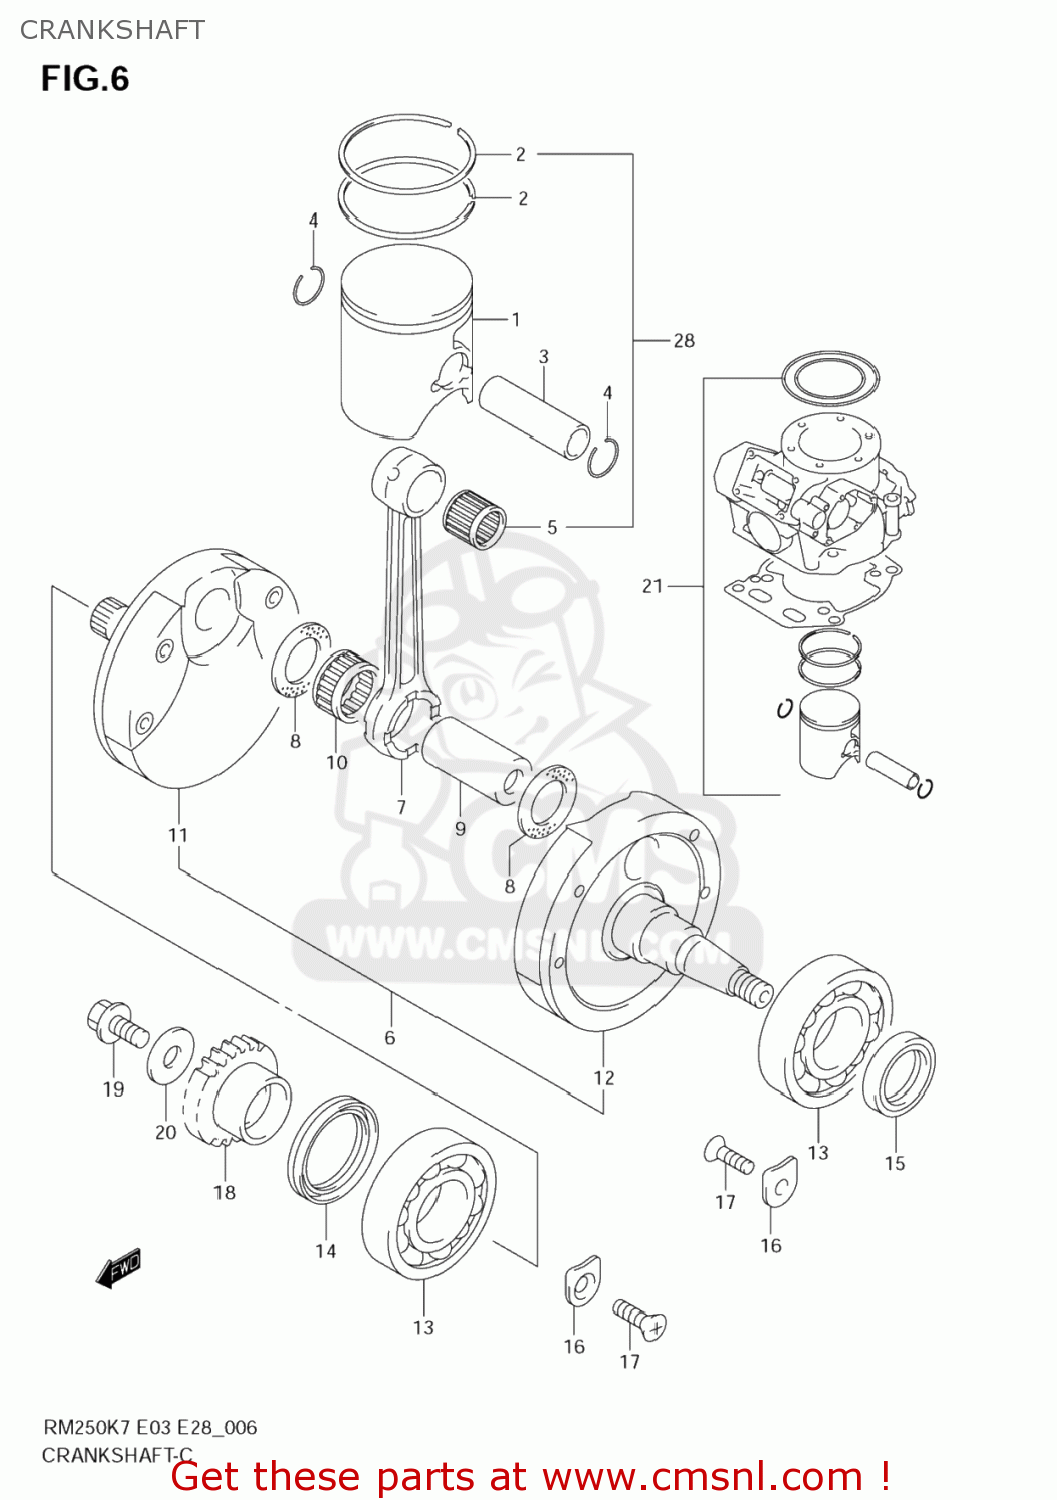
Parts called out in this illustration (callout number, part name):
1	PISTON
2	RING,PISTON
3	PIN,PISTON
4	CIRCLIP
5	BEARING(18X23X22)
6	CRANKSHAFT ASSY
7	CONNECTING ROD
8	WASHER(24X39X1)
9	PIN,CRANK
10	BEARING(24X30X20)
11	CRANKSHAFT,R
12	CRANKSHAFT,L
13	BEARING(28X68X18)
14	SEAL,OIL(28X38X19)
15	SEAL,OIL(25X37X7)
16	RETAINER,CRANKSHAFT BEARING
17	SCREW
18	GEAR,PRIMARY DRIVE
19	BOLT(10X20)
20	WASHER
21	TOP END KIT,ENGINE
22	O RING,CYLINDER HEAD NO.1
23	O RING,CYLINDER HEAD NO.2
24	GASKET,CYLINDER (NAS)
25	PISTON
26	RING,PISTON
27	CIRCLIP
28	PISTON KIT
29	PISTON
30	RING,PISTON
31	PIN,PISTON
32	BEARING(18X23X22)
33	CIRCLIP
